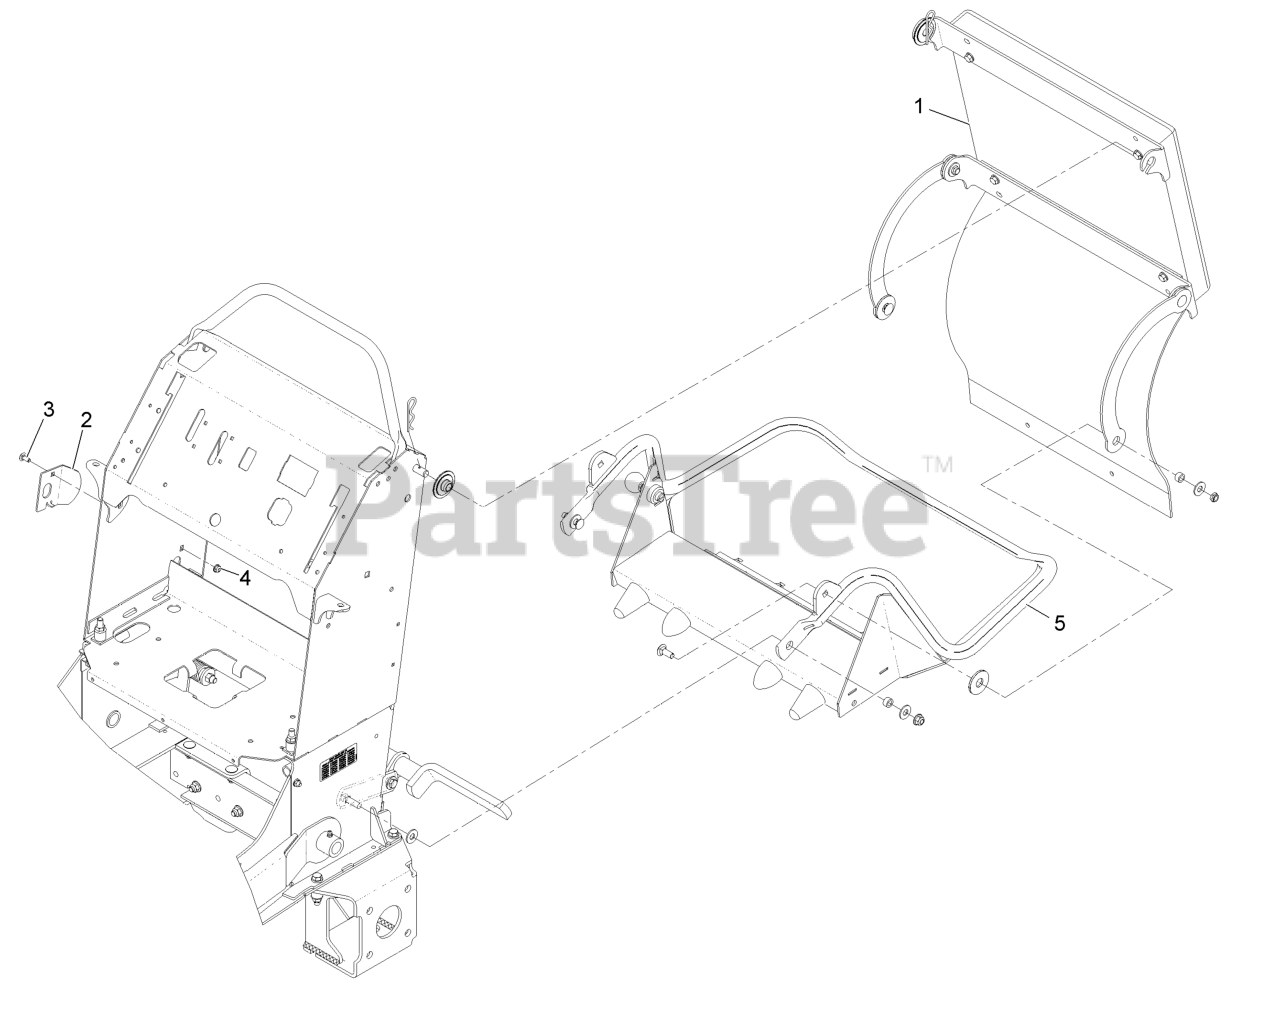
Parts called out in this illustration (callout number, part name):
2	PLATE-STRIKER
3	SCREW-CARR
5	ASM,PLATFORM
